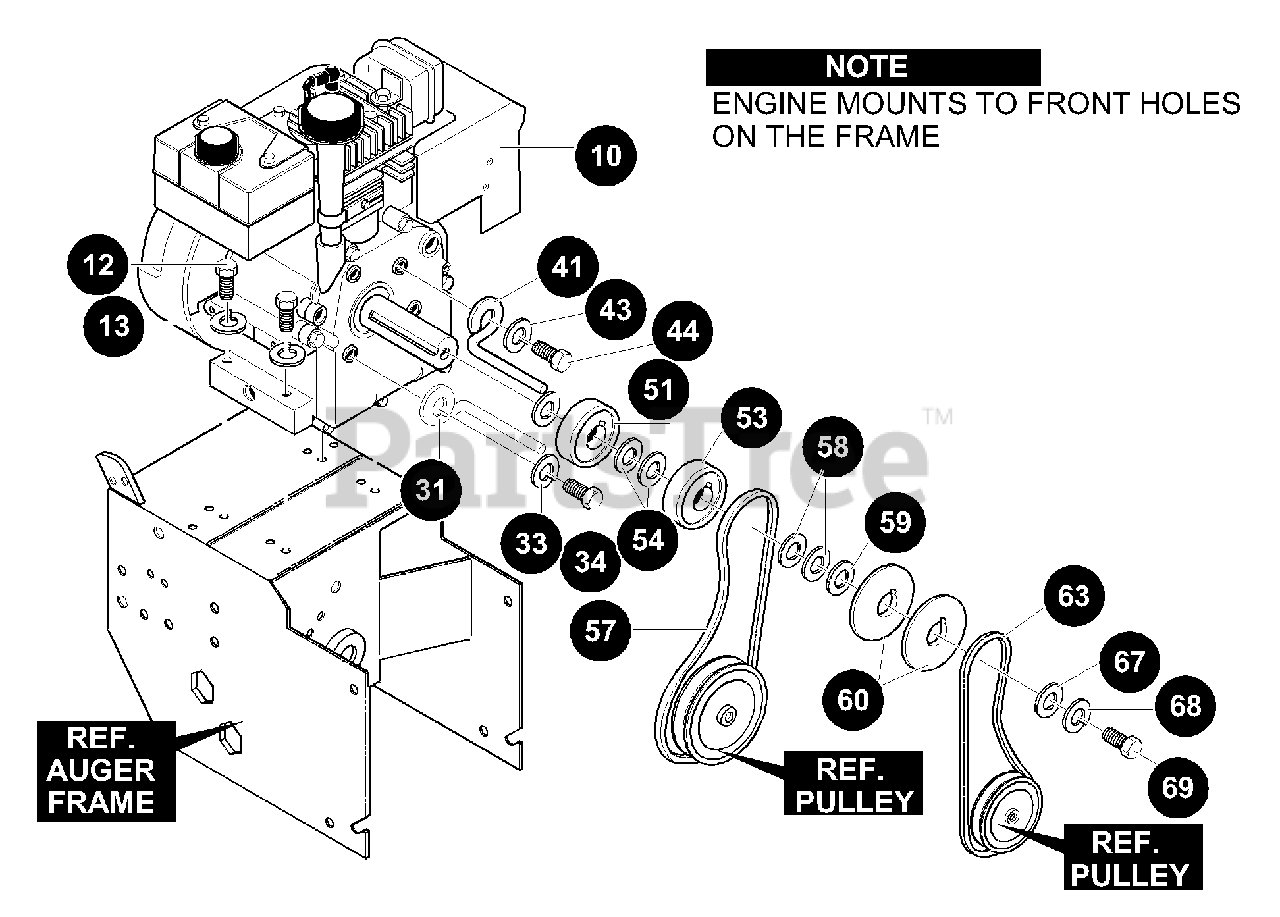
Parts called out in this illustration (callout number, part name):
10	ENGINE, 7 HP
12	SCREW, 5/16-18X.75
13	WASHER, .328X.60X.09
31	GUIDE, ROD BELT RH
33	WASHER, .328X.60X.09
34	SCREW, 5/16-24X .625HHC
41	GUIDE, ROD BELT RH
43	WASHER, .328X.60X.09
44	SCREW, 5/16-24X .625HHC
51	WASHER, CRANKSHAFT
53	PULLEY, HALF
54	FLATWASHER .752X .91X.02
57	BELT, V 3L 33.13LG
58	FLATWASHER .765X1.12X.06
59	SPACER, SLEEVE
60	PULLEY, ENGINE
63	BELT, V 4L 36.6
67	WASHER, FLAT
68	WASHER, .393X.68X.10
69	SCREW, 3/8-24X1.00
